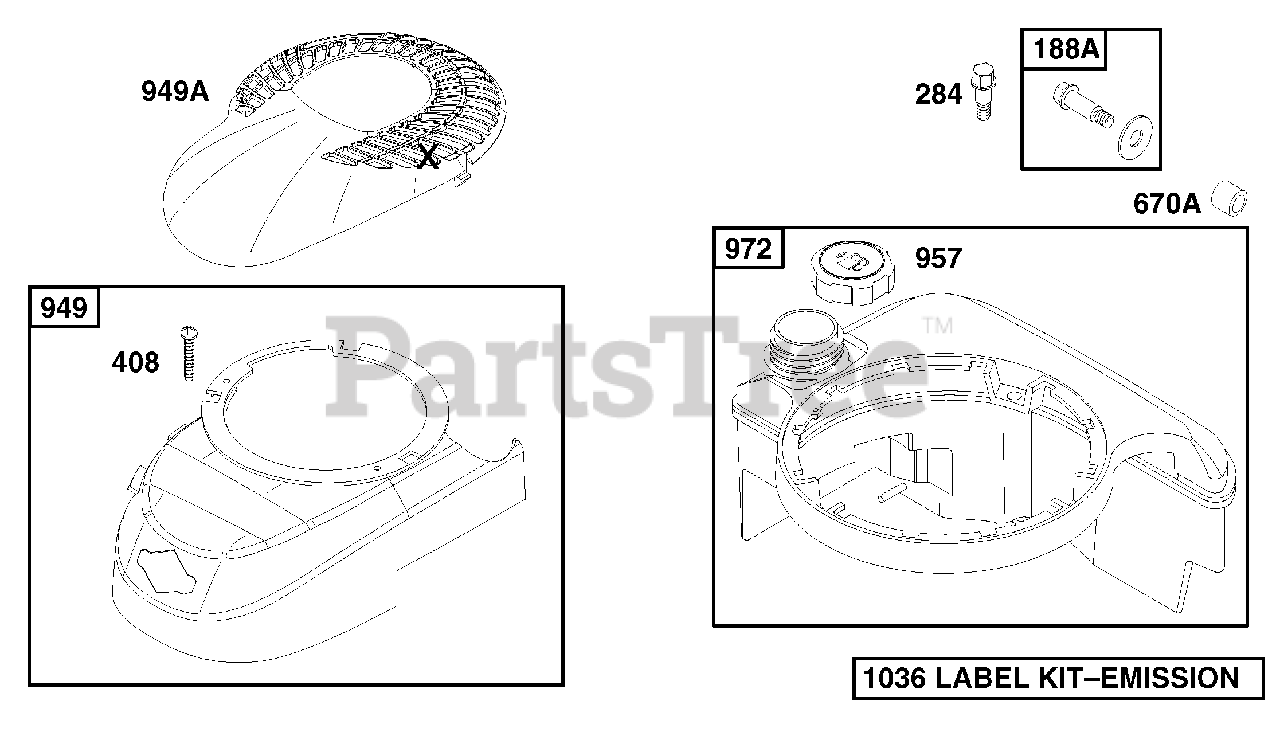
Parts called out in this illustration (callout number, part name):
188A	Screw-Washer Kit
284	Screw-Shoulder
408	Screw-Phillips
670A	Spacer-Fuel Tank
949	Guard-Rewind
949A	Guard-Rewind
957	Cap-Fuel Tank
972	Tank-Fuel
1036	Label Kit-Emission
